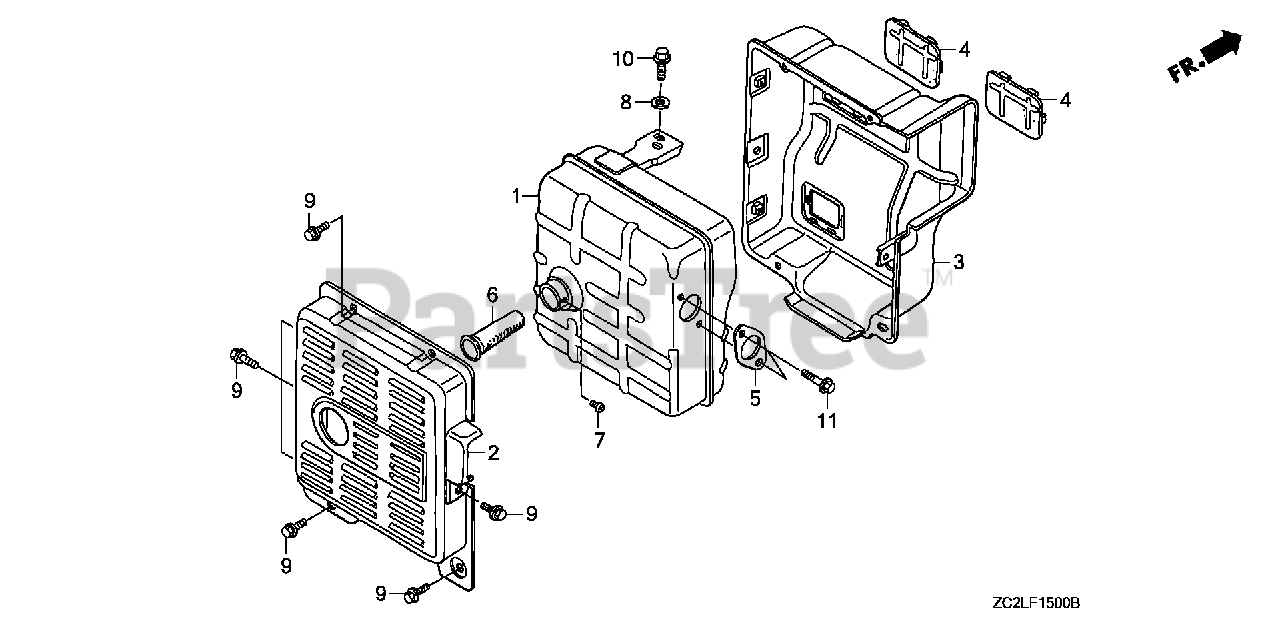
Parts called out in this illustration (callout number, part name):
1	MUFFLER (SANKEI)
2	PROTECTOR, MUFFLER (OUTER)
3	PROTECTOR, MUFFLER (INNER)
4	SEAL, MUFFLER PROTECTOR
5	GASKET, EX. PIPE
6	ARRESTER, SPARK
7	SCREW, TAPPING (4X8)
8	WASHER, PLAIN (8MM)
9	BOLT, FLANGE (6X10)
10	BOLT, FLANGE (8X16)
11	BOLT, FLANGE (8X20)
